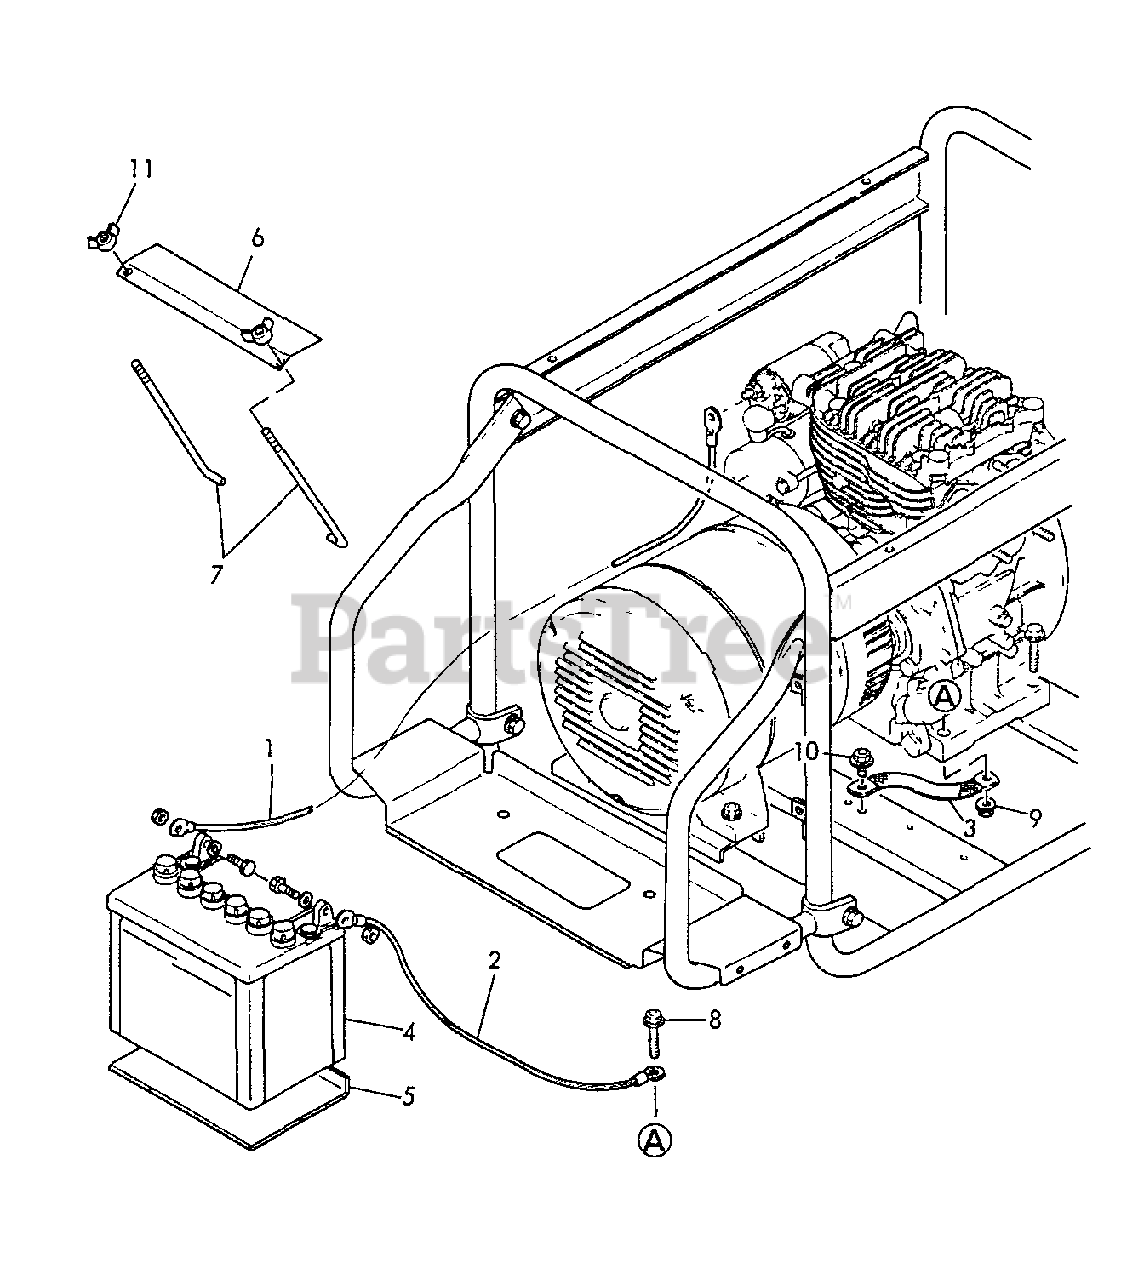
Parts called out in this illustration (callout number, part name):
1	CABLE -- ( + )
2	CABLE -- ( - )
3	CABLE -- ( - )
4	BATTERY 12V - 24AH
5	SHEET, BATTERY
6	RETAINER, BATTERY
7	BOLT, BATTERY
8	BOLT - 8×30 -- PLATED
9	U-NUT M8
10	BOLT - 6×8 -- PLATED
11	WINGNUT - 6
